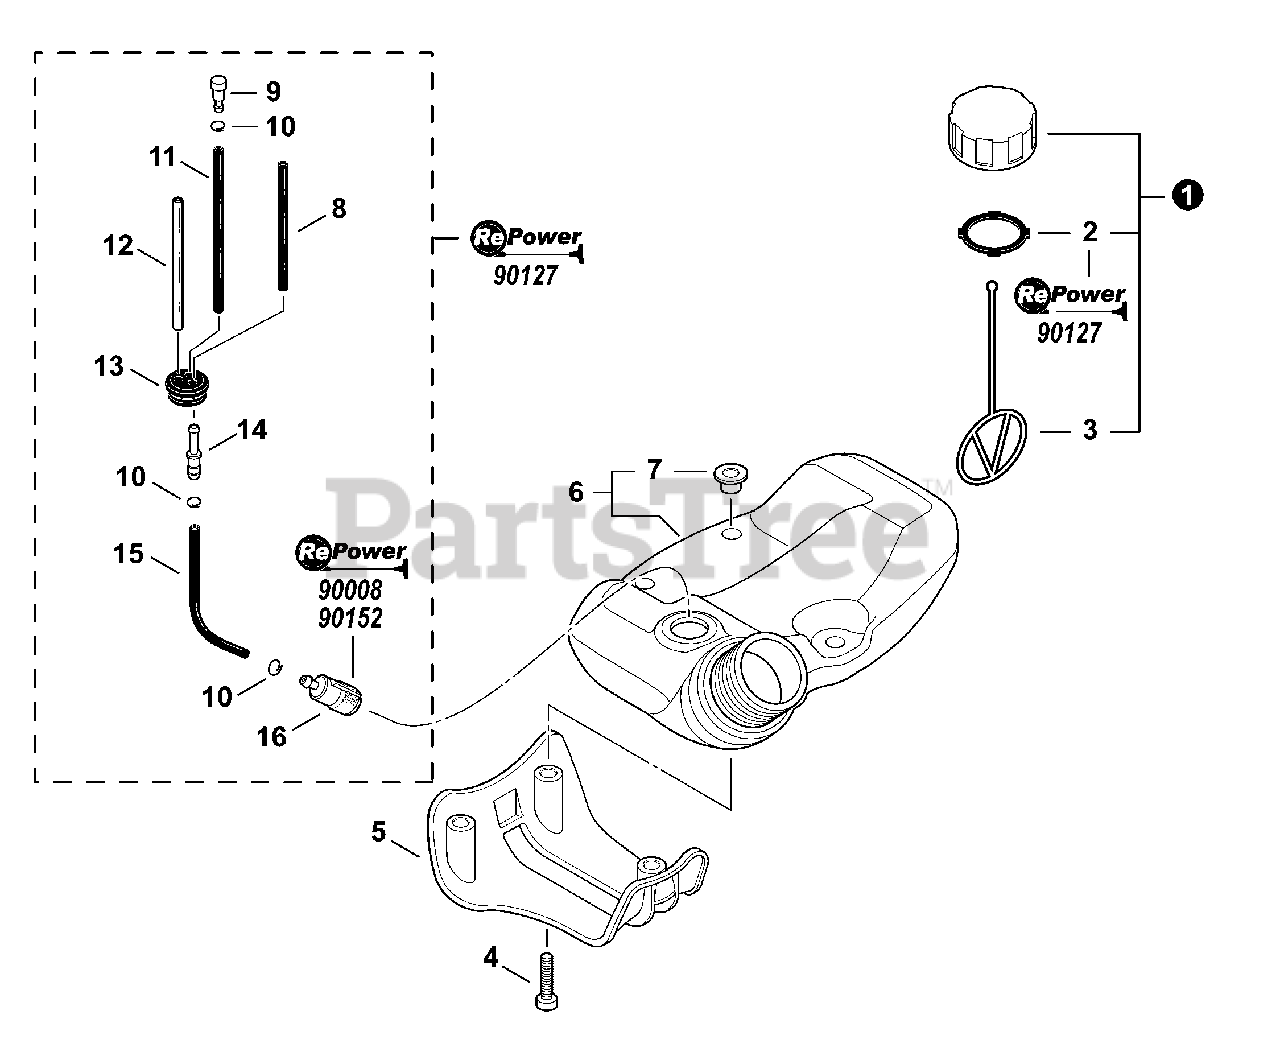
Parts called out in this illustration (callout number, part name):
1	CAP ASSY
2	GASKET, CAP
3	CONNECTOR, CAP
4	SCREW - 5×20
5	GUARD, FUEL TANK
6	FUEL TANK ASSY
8	PIPE - 3×5×74 -- BLACK
9	VENT, FUEL TANK
10	CLIP - 6
11	PIPE - 3×5×90 -- BLACK
12	PIPE - 3×6×80 -- CLEAR
14	CONNECTOR, FUEL PIPE
15	PIPE - 3×5×130 -- BLACK
16	FILTER, FUEL
